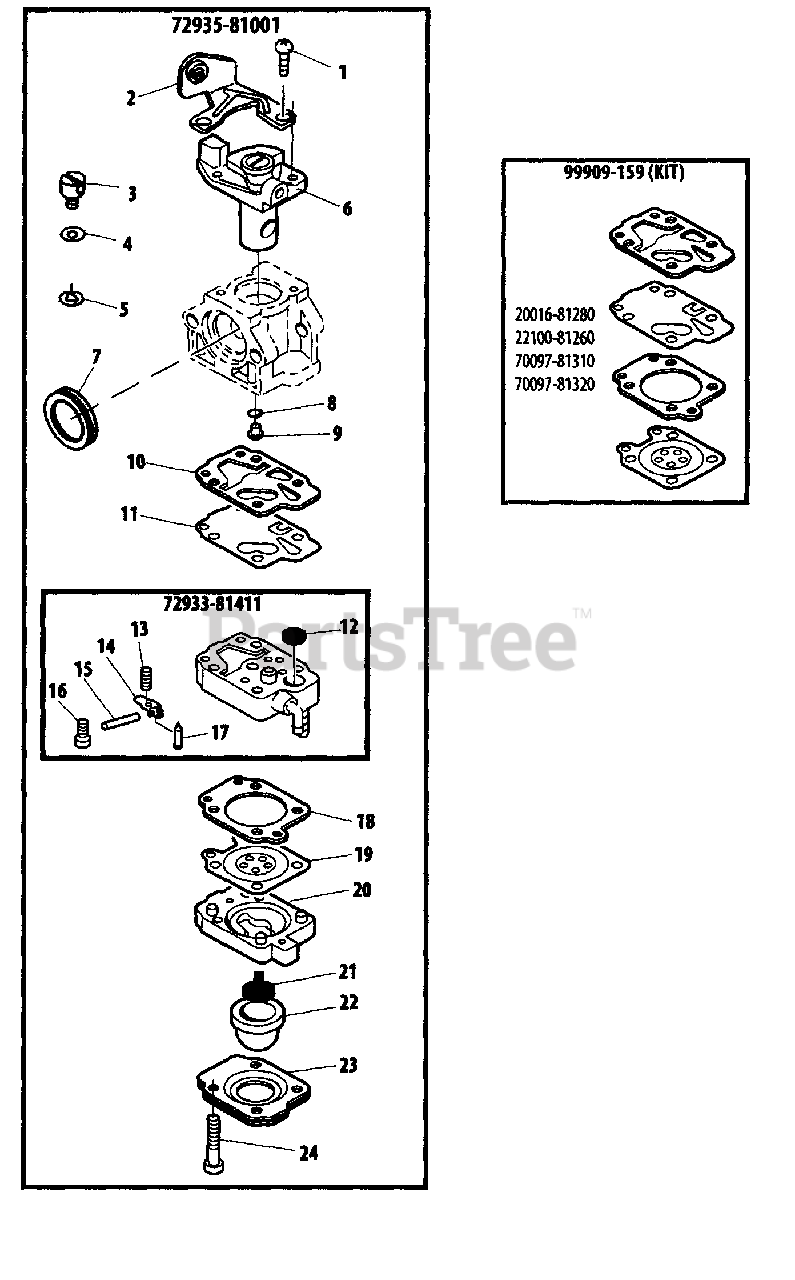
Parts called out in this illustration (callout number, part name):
1	SCREW
2	BRACKET, THROTTLE CABLE
3	SWIVEL
4	WASHER
5	E-RING
6	THROTTLE VALVE ASSY
7	RING, PACKING
8	O-RING
9	JET
10	GASKET, PUMP
11	DIAPHRAGM, PUMP
12	SCREEN, FUEL INLET
13	SPRING, METERING LEVER
14	LEVER, METERING
15	PIN, METERING LEVER
16	SCREW
17	VALVE, INLET NEEDLE
18	GASKET, METERING DIAPHRAGM
19	DIAPHRAGM, METERING
20	BODY ASSY, PURGE
21	VALVE, CHECK
22	BULB, PURGE
23	RETAINER, PURGE BULB
24	SCREW
72933-81411	BODY ASSY, PUMP
72935-81001	CARBURETOR
99909-159	GASKET / DIAPHRAGM KIT
